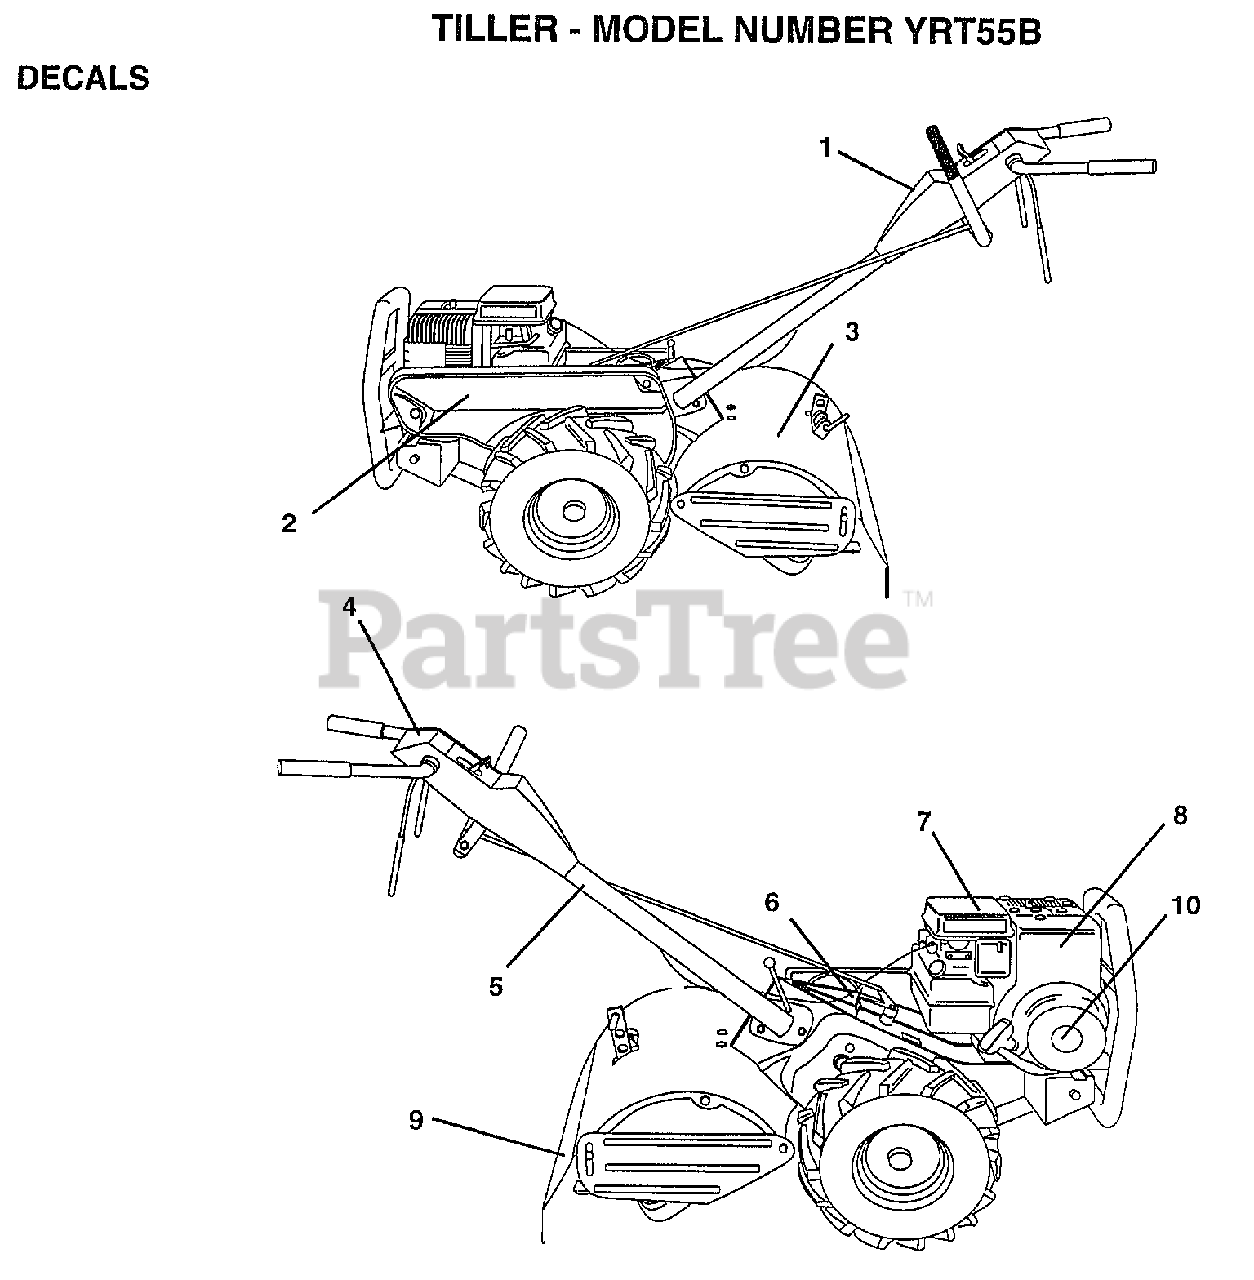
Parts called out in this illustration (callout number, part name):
1	DECAL PANEL CNTRL
2	DECAL GUARD BELT
3	DECAL SHIELD TINE
4	DECAL.INSTRUCTION
5	DECAL TI
6	DECAL CRT
7	DECAL.CAUTION
8	DECAL, BRIGGS & STRATTON
10	DECAL, 5.5HP
